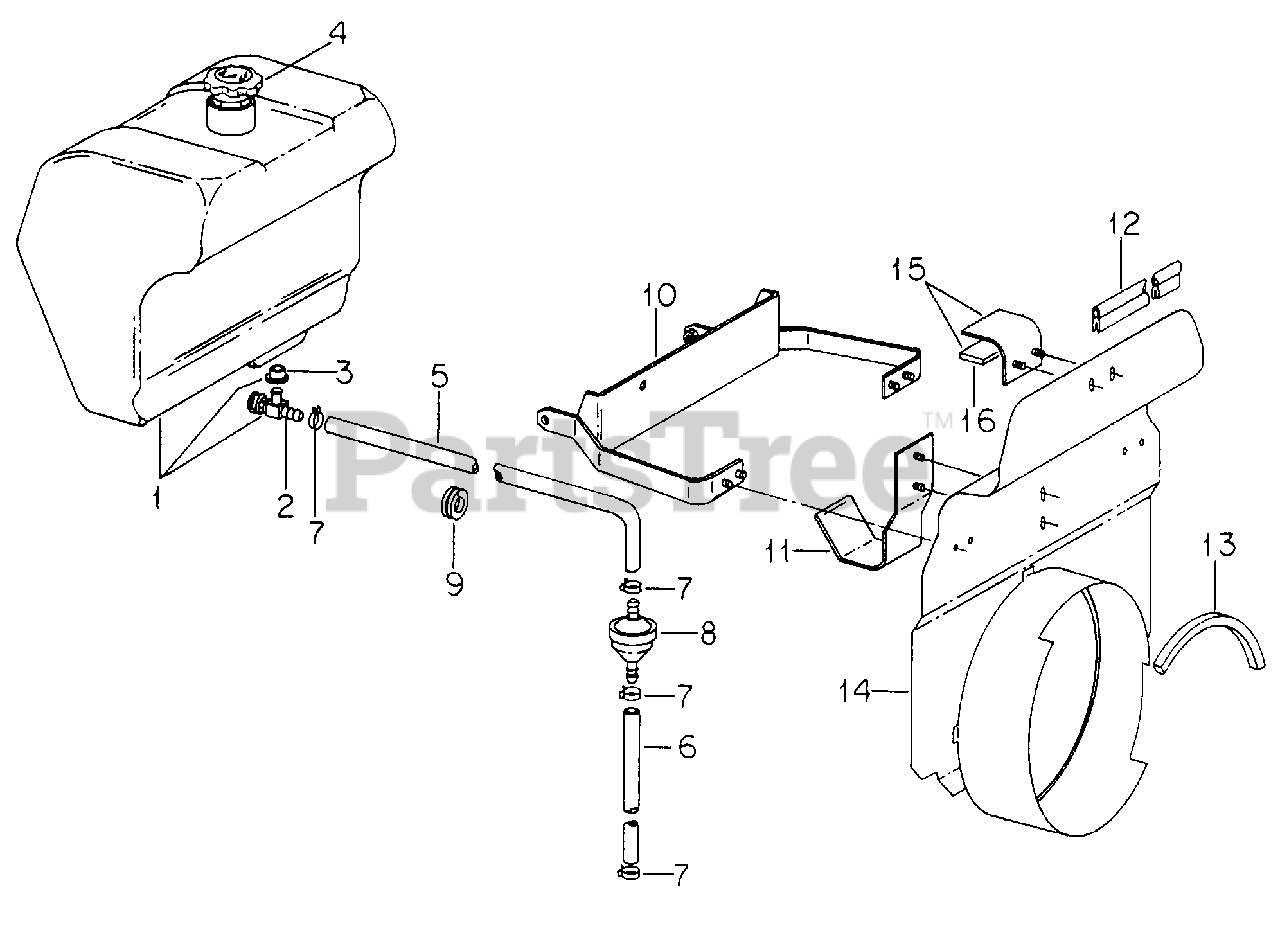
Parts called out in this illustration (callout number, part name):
1	Tank Assy, Fuel
2	Valve, Shut-Off
3	Bushing
4	Cap w/Gauge Assy
5	Line, Fuel
6	Line, Fuel
7	Clamp, Hose
8	Filter, Fuel
10	Support Assy, Fuel Tank
11	Support Assy, Fuel Tank Bottom
12	Seal, Heat Baffle
13	Not used in this application
14	Deflector Assy, Heat
15	Clamp Assy, Fuel Tank
16	Strip, Fuel Tank Pad
